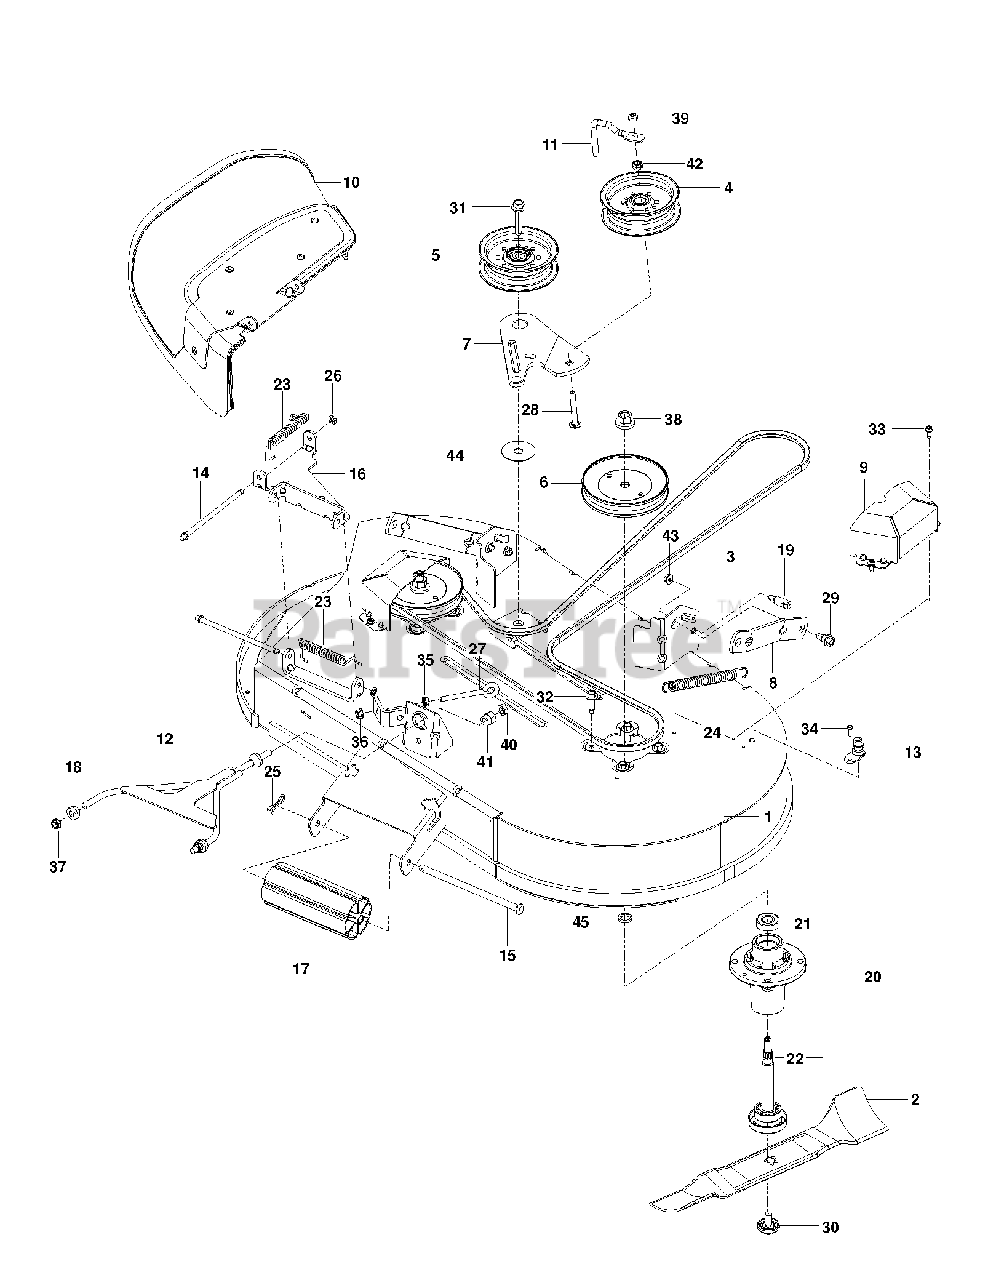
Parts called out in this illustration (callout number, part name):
2	Mower Blade, 42" FCS Bagging
3	Drive Belt, 42" Deck FCS ZTR
4	PULLEY.IDLER.2006
5	PULLEY.IDLER.MWR.STATI
6	PULLEY MANDREL 5.0"
7	ARM.42"FCS.CLUTCHING.X431
8	ARM.RFIXED.MOWER.SUSPNSIONX431
10	Deflector Assembly, 42" FCS Orange
11	KEEPER.BELT.IDLER.54"T
12	LINK.FRONT.WLDMNT.RZ X431
13	PORT.WASHOUT
14	ROD.HINGE
15	ROD.ROLLER.NOSE.NARROW.48"
17	NOSE ROLLER 48"
18	BUSHING SPHERICAL SUSP. FRONT
19	STUD.FASTNER.W/ANTI-ROTATE
20	MANDREL ASM, CAST IRON
22	SHAFT ASM MANDREL
23	Deflector Spring, 42 FCS
24	SPRING.MOWER.DRIVE.ELECTRIC
25	PIN.COTTER.5/16.BOW TI
26	NUT PUSH M
27	EYE BOLT 5/16 X 3.50
28	BOLT
29	BOLT.SHOULDER
30	BOLT.WASHER.ASM.7/16-2
31	Screw, 7/16-14 X 2.125.Washer
32	SCREW, WASHER HEAD
33	SCREW.1/4-20X5/8
35	NUT 5/16C WHIZ
36	5/16-18 NYLOC FLANGE NUT
37	NUT, 7/16-20 HEX NYLOC ZC
38	LOCKNUT - 9/16
39	LOCKNUT
41	NUT, LIFT LINK 7/16-20
42	NUT LOCK FLG 3/8-16 UNC
43	NUT LOCK HEX FLANGE 5/16-18
45	WASHER.SPACER.MANDREL
